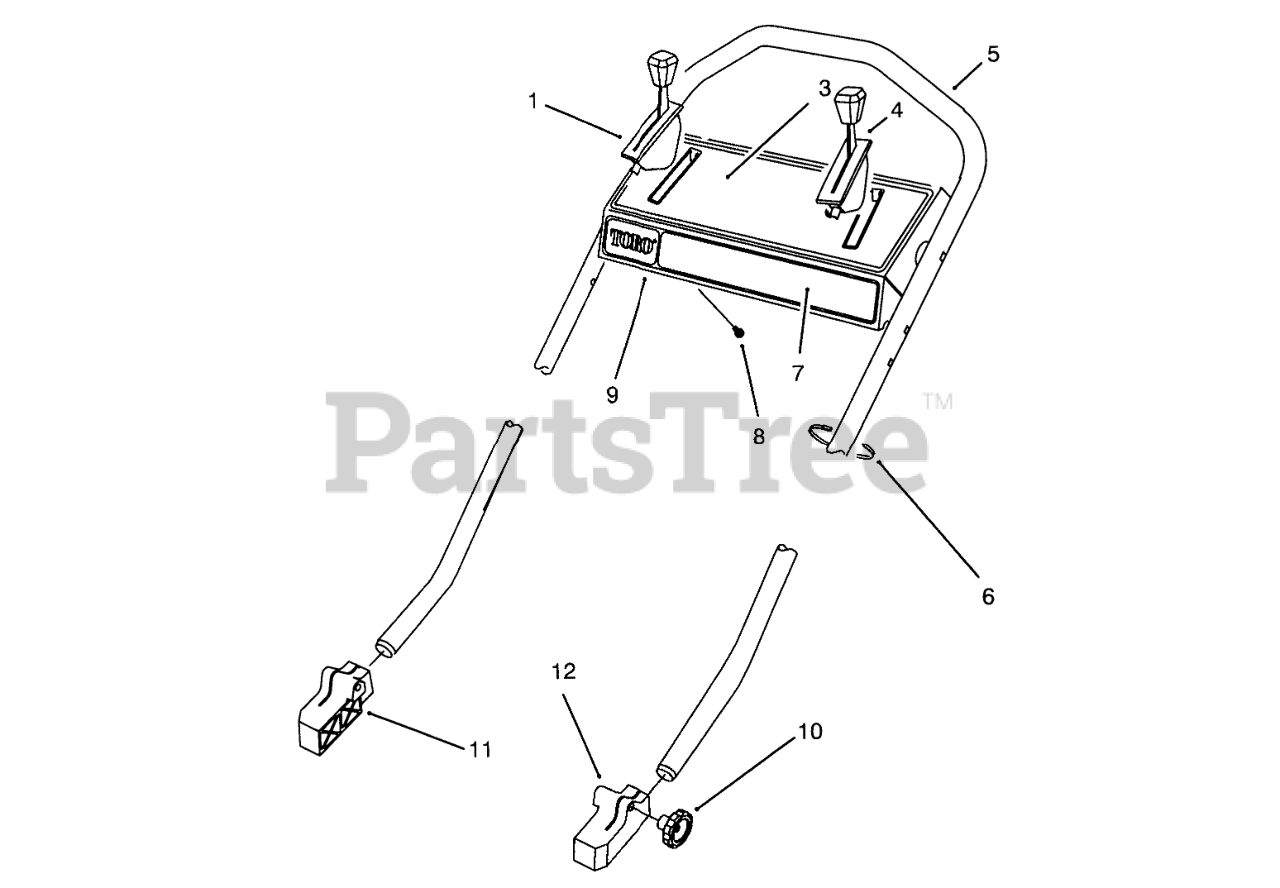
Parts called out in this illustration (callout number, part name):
1	GROUND SPEED CONTROL
3	DECAL - INSTRUCTION
4	CONTROL - THROTTLE
5	HANDLE PVC DIP
6	TIE-CABLE
7	DECAL-PANEL
8	SCREW-HWHTF
9	Control Panel Assembly (Incl. Ref. #3, & 7)
11	MOUNT-HANDLE, RH
12	MOUNT-HANDLE, LH
